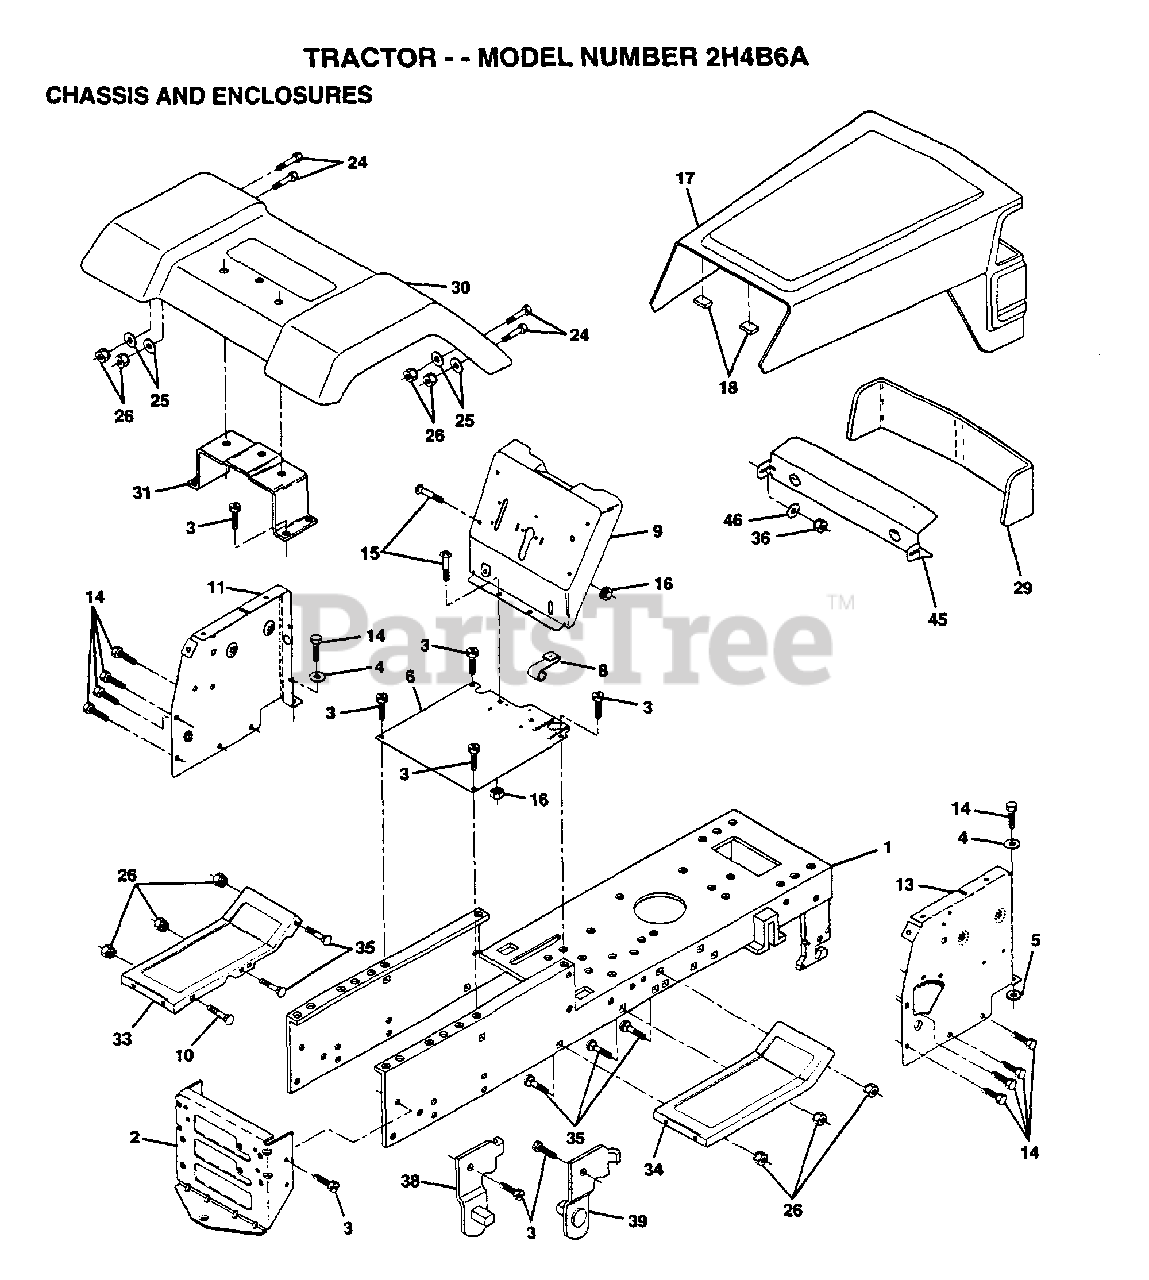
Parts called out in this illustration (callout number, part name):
3	SCREW
4	WASHER
5	LOCKWASHER
8	"CLIP,INSULATOR"
9	DASH SILKSCRN 1
11	DASH PANEL LH
14	SCREW LT
15	SCREW
17	HOOD/GRILL ASM
24	BOLT
25	WASHER
26	NUT
31	BRKT FENDER
33	FOOTREST LH
34	FOOTREST RH
35	BOLT
36	PAL NUT LT
38	BRACKET ASM LH
39	BRACKET ASM RH
46	RETAINER
